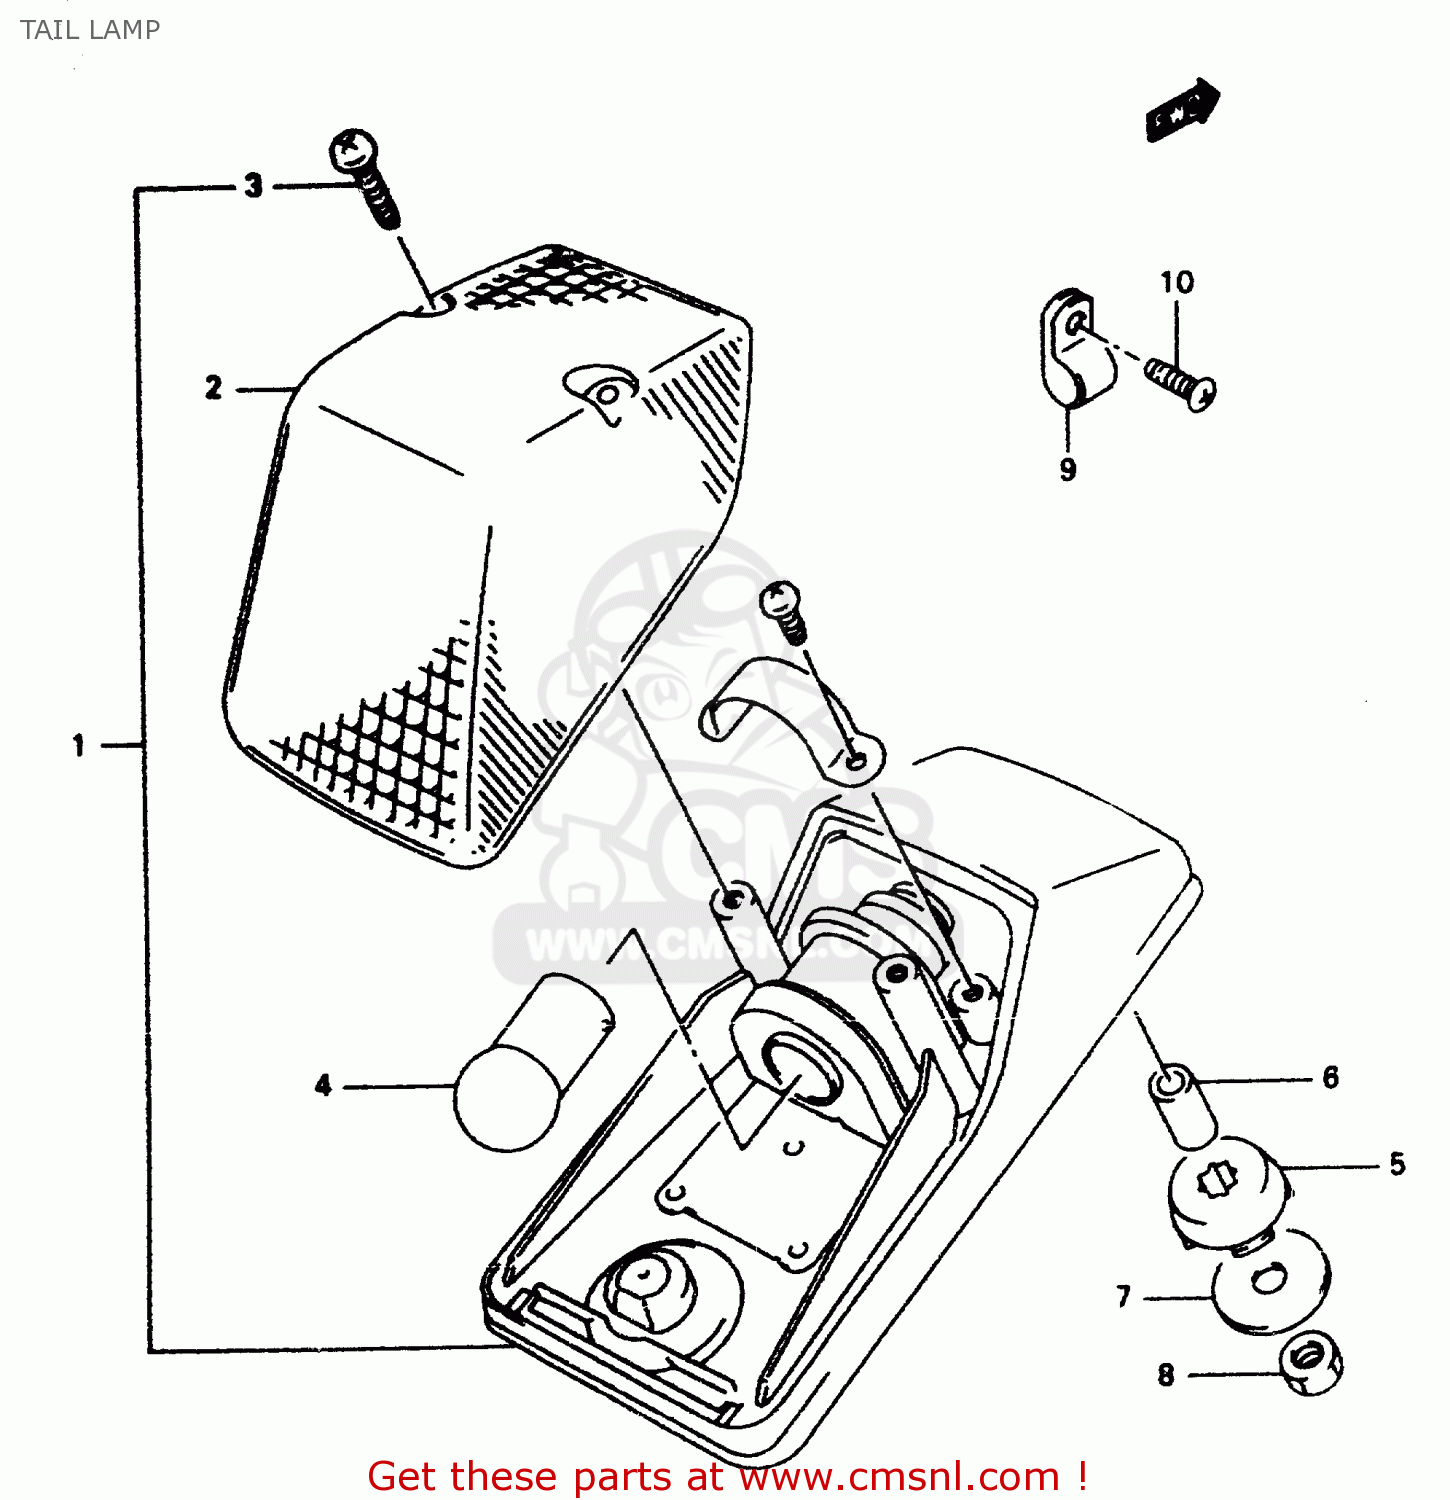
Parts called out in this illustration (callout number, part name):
1	LAMP ASSY,TAIL
2	LENS
3	SCREW
4	BULB(12V5W,BF150-40160A)
5	CUSHION
6	SPACER(6.4X9.2X12)
7	WASHER(6.5X20X1.2)
8	NUT 6MM
9	CLAMP
10	SCREW
11	RR ASSY,RR
12	REFLEX REFLECTOR,RR
13	BRACKET,REAR REFLECTOR
14	NUT
15	NUT
